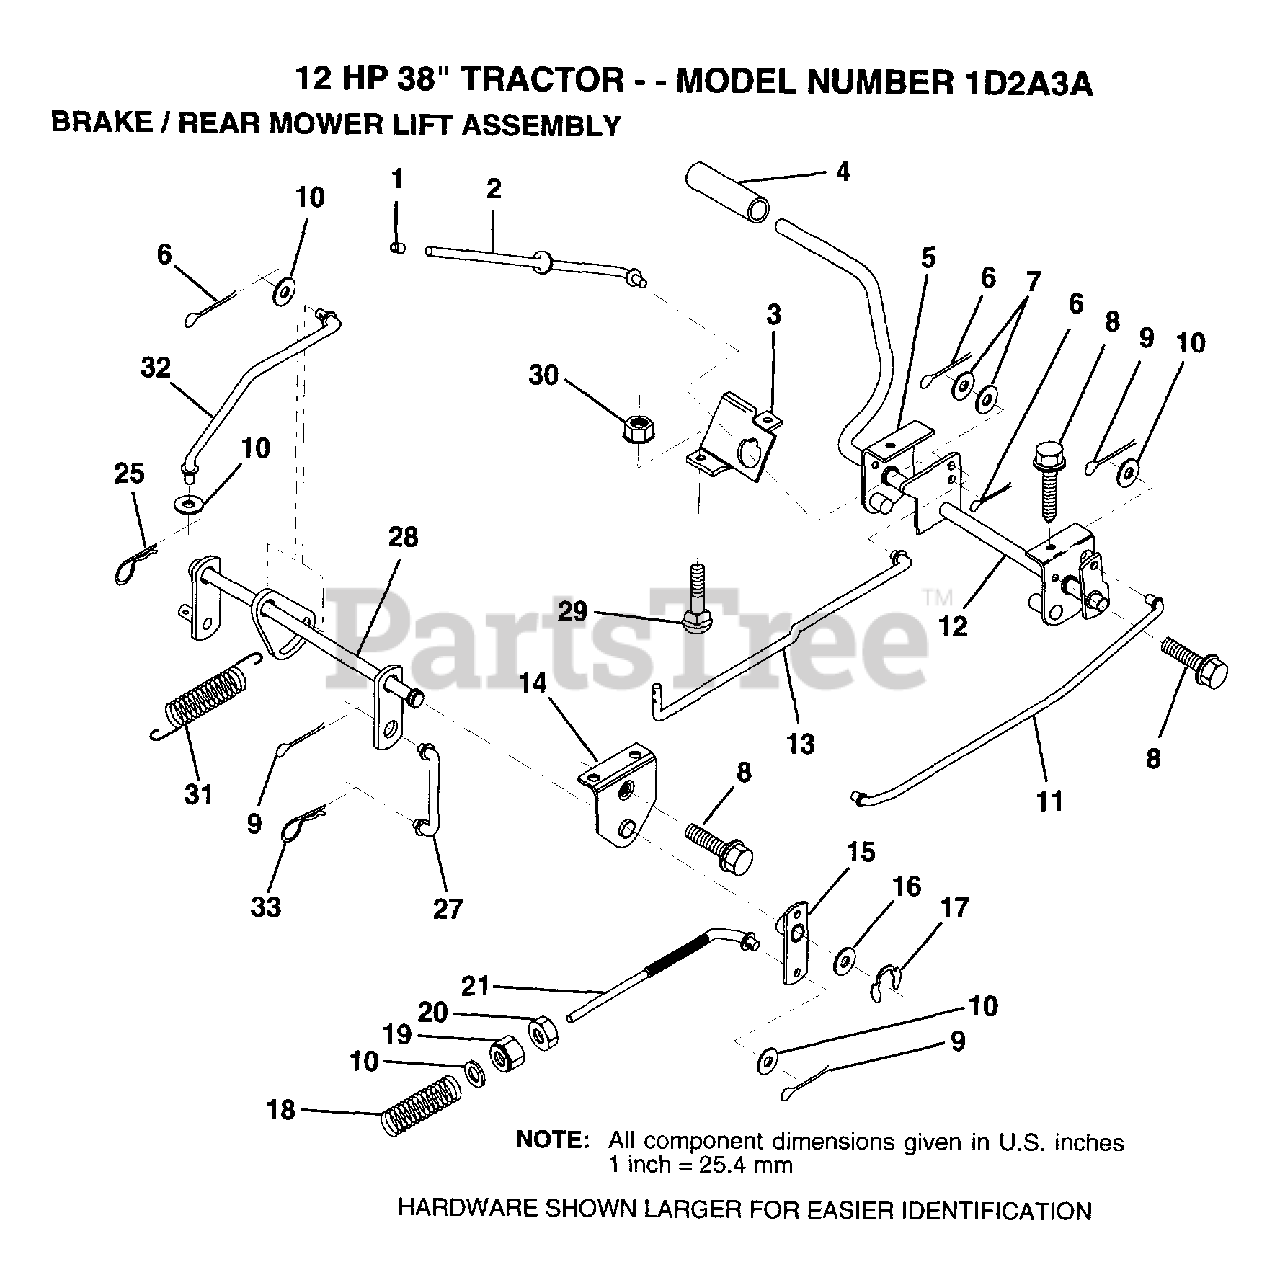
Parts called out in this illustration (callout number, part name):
1	PLUNGER CAP T
2	"ROD,PARK BRAKE"
3	"BRKT,PARK BRAKE"
4	PEDAL COVER T
5	BRK ASM CLUT LH
7	WASHER
8	SCREW LT
9	COTTER PIN
10	WASHER
11	"ROD,FRT BRAKE"
12	ASM CLUTCH/BRK PD
13	"ROD,CLUTCH"
14	"BRKT,LIFT SHAFT"
15	BRAKE PIVOT ARM
16	WASHER T
17	KLIP RING
18	SPRING ROD LT
19	NUT
20	NUT.LK.W/WSH.1/2.
21	ROD.BRAKE.REAR
25	SPRING.RETAINER
27	LINK LIFT REAR LR
28	LIFT ASM MWR RE
31	COUNTER SPRING
32	LINK LIFT LEVER
